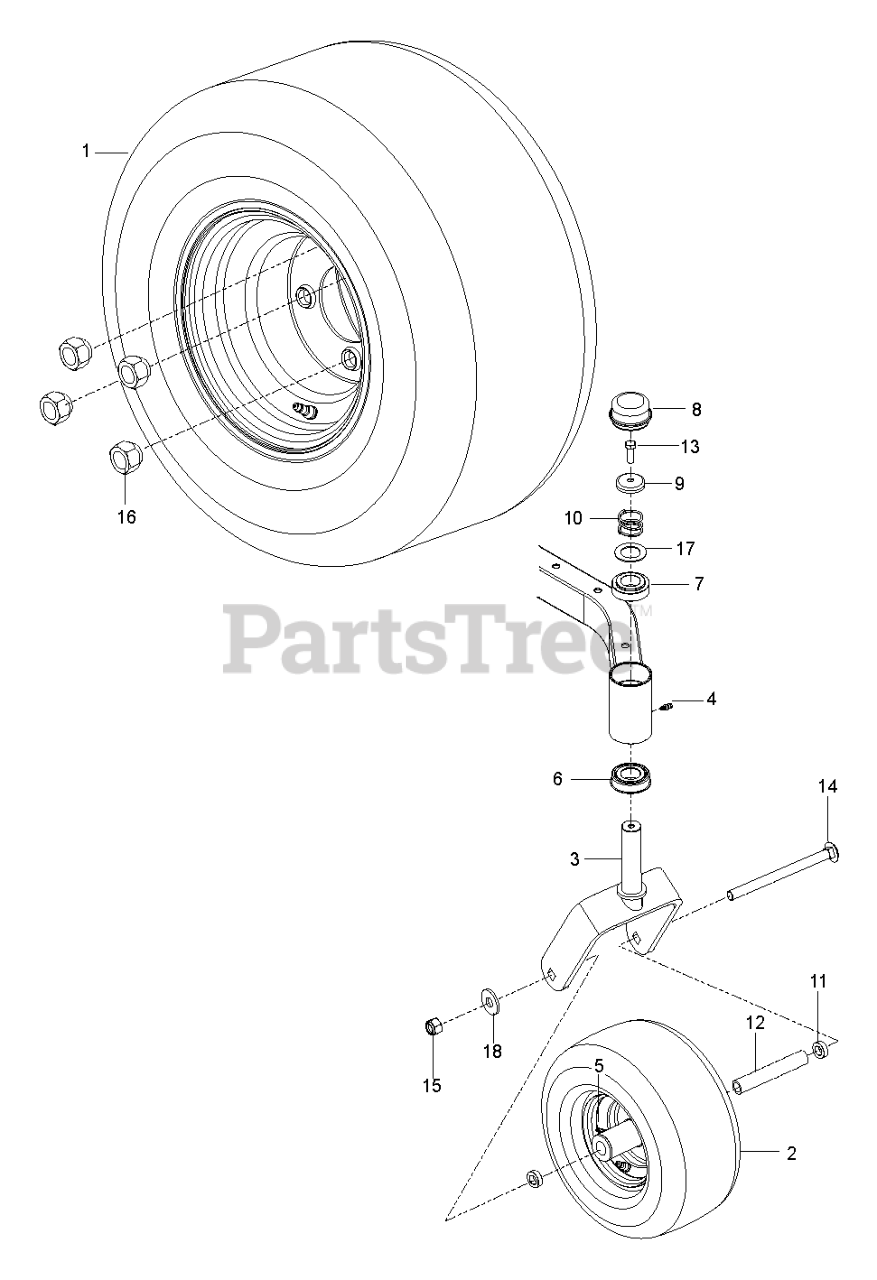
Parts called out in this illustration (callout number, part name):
1	WHEEL CARLSTAR 18X9.5-8" SILVE
2	WHEEL.CARLSTAR.11X4-5".MS417
3	YOKE.CASTER.ORANGE
4	ZERK, 3/16, DRIVE IN
5	ZERK
6	BEARING FLANGED
7	BUSHING, CASTER
8	GREASE CAP
9	CASTER.PLUG
10	SPRING, CASTER
11	SPACER 5/16"
12	SPACER, PIVOT
13	5/16-18X1 HHB G5W/NY
14	RHSNB 1/2-13 X 6.50 GR5 ZD
15	NUT. 1/2-13 HEX CNTRLK GR 5 ZD
16	NUT.1/2-20.UNF-2B.GR.8.YL
17	WASHER, 1.025 ID X 1.64
18	WASHER.9/16 X 1 3/8 X 12 GA.
